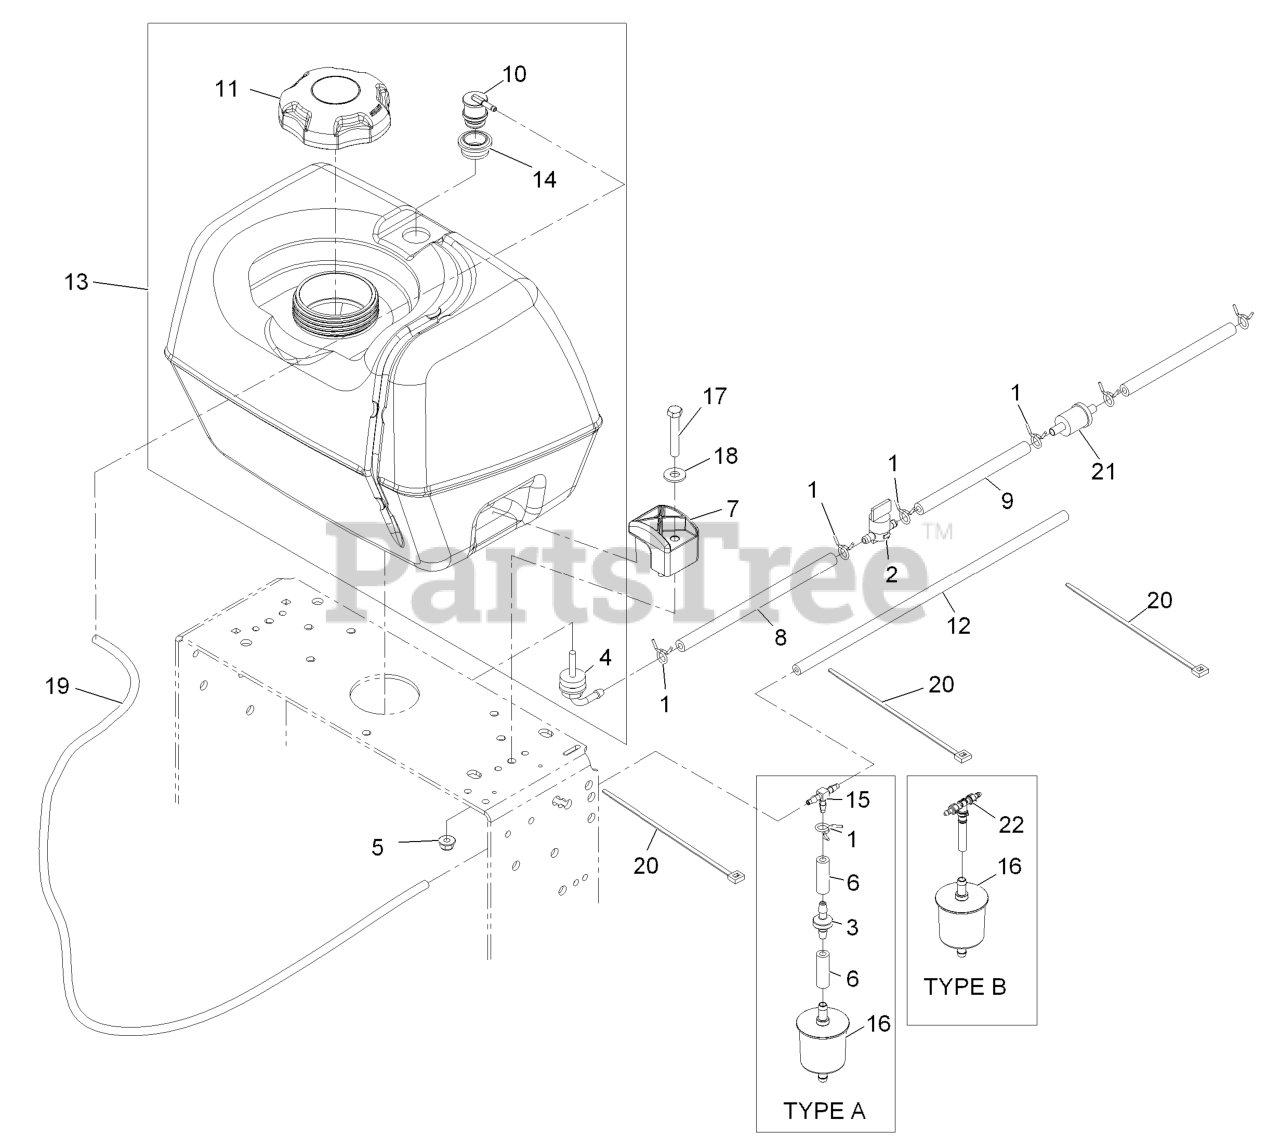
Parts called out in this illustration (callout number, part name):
1	CLAMP-HOSE
2	VALVE-FUEL
3	VALVE-CHECK, FUEL
4	FITTING-FUEL, BULKHEAD
5	NUT-HF, NI
6	HOSE-FUEL
8	HOSE-FUEL
9	HOSE-FUEL
12	HOSE-FUEL
14	GROMMET
15	FITTING-TEE
16	FILTER-FUEL
17	SCREW-HH
18	WASHER-FLAT
19	HOSE-EMISSIONS
20	TIE-PLASTIC
21	Pn 41019-1055 Filter W/6in Fuel Line
22	TEE AND CHECK
